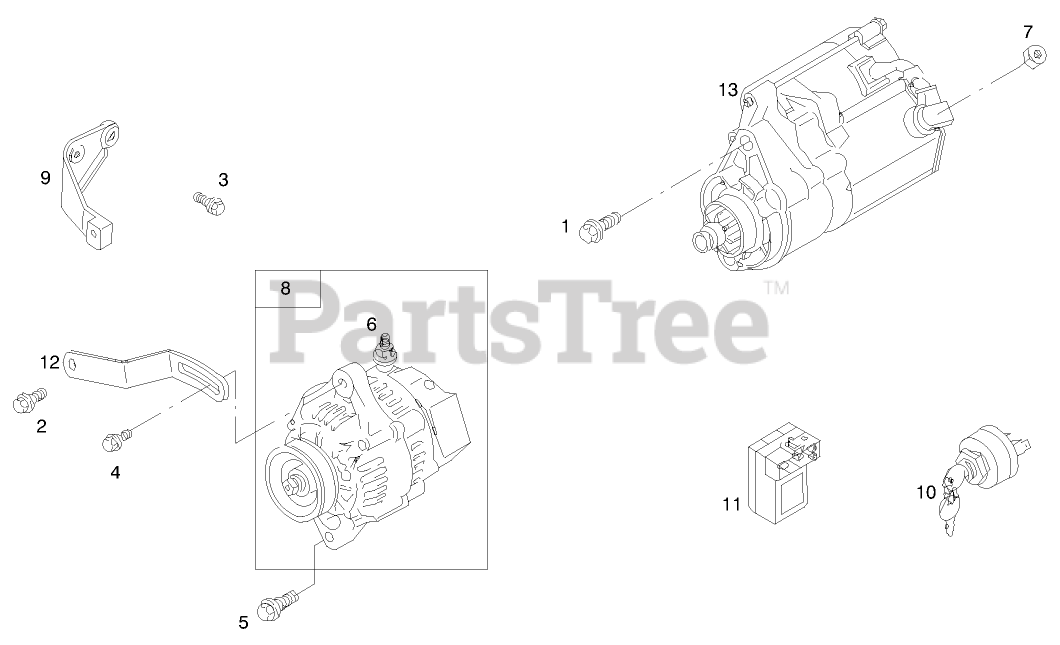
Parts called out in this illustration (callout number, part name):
1	SCREW-HEX
2	SCREW-HEX
3	SCREW-HEX
4	SCREW-HEX, METRIC
5	SCREW-HEX, METRIC
6	NUT-HEX, METRIC
7	NUT-HEX, METRIC
8	ALTERNATOR
9	BRACKET-SUPPORT
10	KEY SWITCH
12	BRACKET-ADJUSTING
